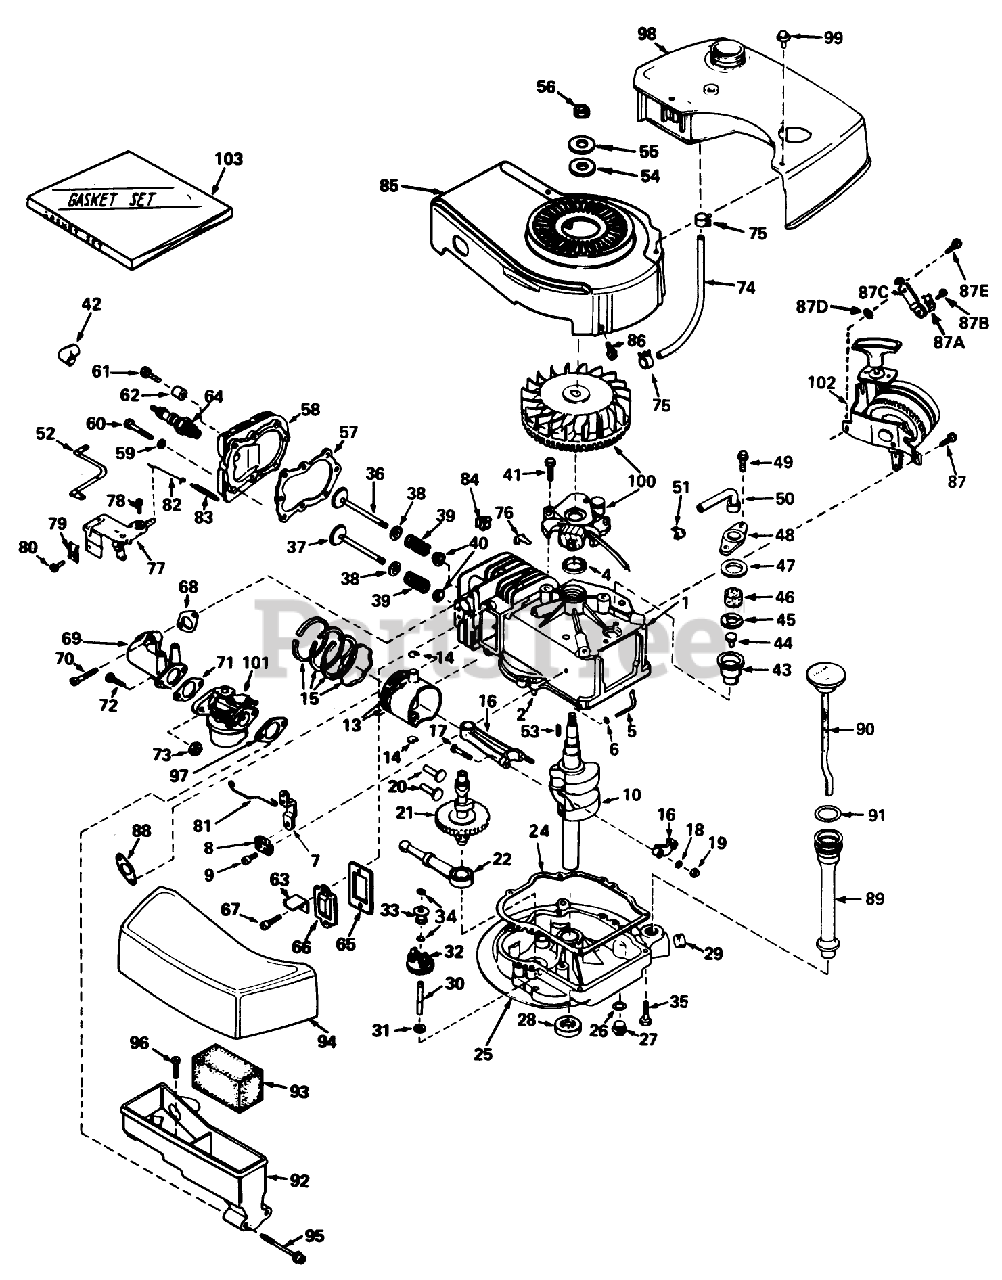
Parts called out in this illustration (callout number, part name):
1	Cylinder Assy. (Incl. Ref. #2, 4 105)
2	Pin-Dowel
4	OIL SEAL
5	Rod, Governor (Incl. No. 36)
6	Washer-Flat
7	Governor Lever
8	Clamp-Lever, Governor
9	Screw
10	Crankshaft Assembly (Incl. Nos. 12 13)
13	Piston Pin Assembly (Incl. 2 of No. 14) (.010 Oversize)
13	Piston Pin Assembly (Incl. 2 of No. 14) (.020 Oversize)
14	Ring-Retaining, Piston Pin
15	Ring Set Piston (Std.)
15	Ring Set Piston (.010 Oversize)
15	Ring Set Piston (.020 Oversize)
16	Rod Assy., Connecting (Incl. Ref. #17)
17	Bolt, Connecting
18	Washer
19	LOCKNUT
20	Lifter-Valve
21	Camshaft (Compression Release
22	Oil Pump ASM
24	Gasket, Mounting
25	Filter, Air Cleaner
26	Gasket-Oil Drain
27	Plug Oil Drain
28	Seal Oil
29	Plug Oil Drain
30	Shaft-Governor
31	Washer-Flat
32	Governor Gear ASM
33	Spool-Governor
34	Ring-Retaining
35	Screw (1/4-20 x 1-1/4)
36	Valve, Intake (Incl. Ref. #38, 39 40) (Std.)
36	Valve, Exhaust (1/32" Oversize) (Incl. Nos. 8, 9 10)
37	Valve, Exhaust (Standard) (Incl. Nos. 8, 9 10)
37	Valve, Exhaust (1/32" Oversize) (Incl. Nos. 8, 9 10)
38	Cap-Upper Valve Spring
39	Spring-Valve
40	Cap-Valve, Spring
41	Screw
42	Cover-Spark Plug
43	Body Breather Tube
44	Valve Check
45	2000A37 WIZARD ROTA
46	Element-Breather
47	Gasket-Breather
48	Cover Breather
49	Screw, Hex Hd. w/Conical
50	Tube, Breaker
51	Clip, Breather
52	Wire, Ground
53	Key Flywheel
54	Washer Flat
55	Washer-Spring
56	Hex Nut
57	63573 GIL 42 SNWTHW
58	Head Cylinder
59	Washer
60	Screw
61	Screw Hex Hd. Cap
62	Space
63	Retainer Clip
64	Plug, Spark (J17LM or equiv.)
65	Gasket-Breather
66	Cover-Valve
67	Screw
68	Gasket, Intake
69	Pipe, Intake
70	Screw (1/4-20 x 1)
71	Gasket-Carburetor
73	Nut and Lock Washer (1/4-28)
74	Line-Fuel
75	Clamp-Line, Fuel
76	Clip-Wire
77	Control Assy., Speed
78	Screw (10-24 x 3/4)
79	Conduit
80	Screw (10-32 x 3/8)
81	Link Governor
82	Link Governor Spring
83	Spring Governor
84	51004 GIL ROTARY TI
85	Housing, Blower
86	Screw
87	Screw (1/4-20 x 1/2)
87A	Conduit
87B	Screw (10-32 x 3/8)
87C	Bracker
87D	Washer
87E	Screw (1/4-20 X 5/8)
88	Gasket Exhaust
89	Tube, Oil Filler
90	Dipstick, OiI (Incl. No. 91)
91	O-Ring
92	Body Air Cleaner
93	Filer, Air
94	Cove, Air Cleaner
95	Screw Fil Hd.
96	Screw, Hex Hd.
97	Gasket-Air Cleaner
98	Tank Fuel
99	Screw (10-32 x 35/64)
100	Magneto
101	Carburetor (Incl. No. 71)
102	Starter
103	53024/VAR.16HP O/P
